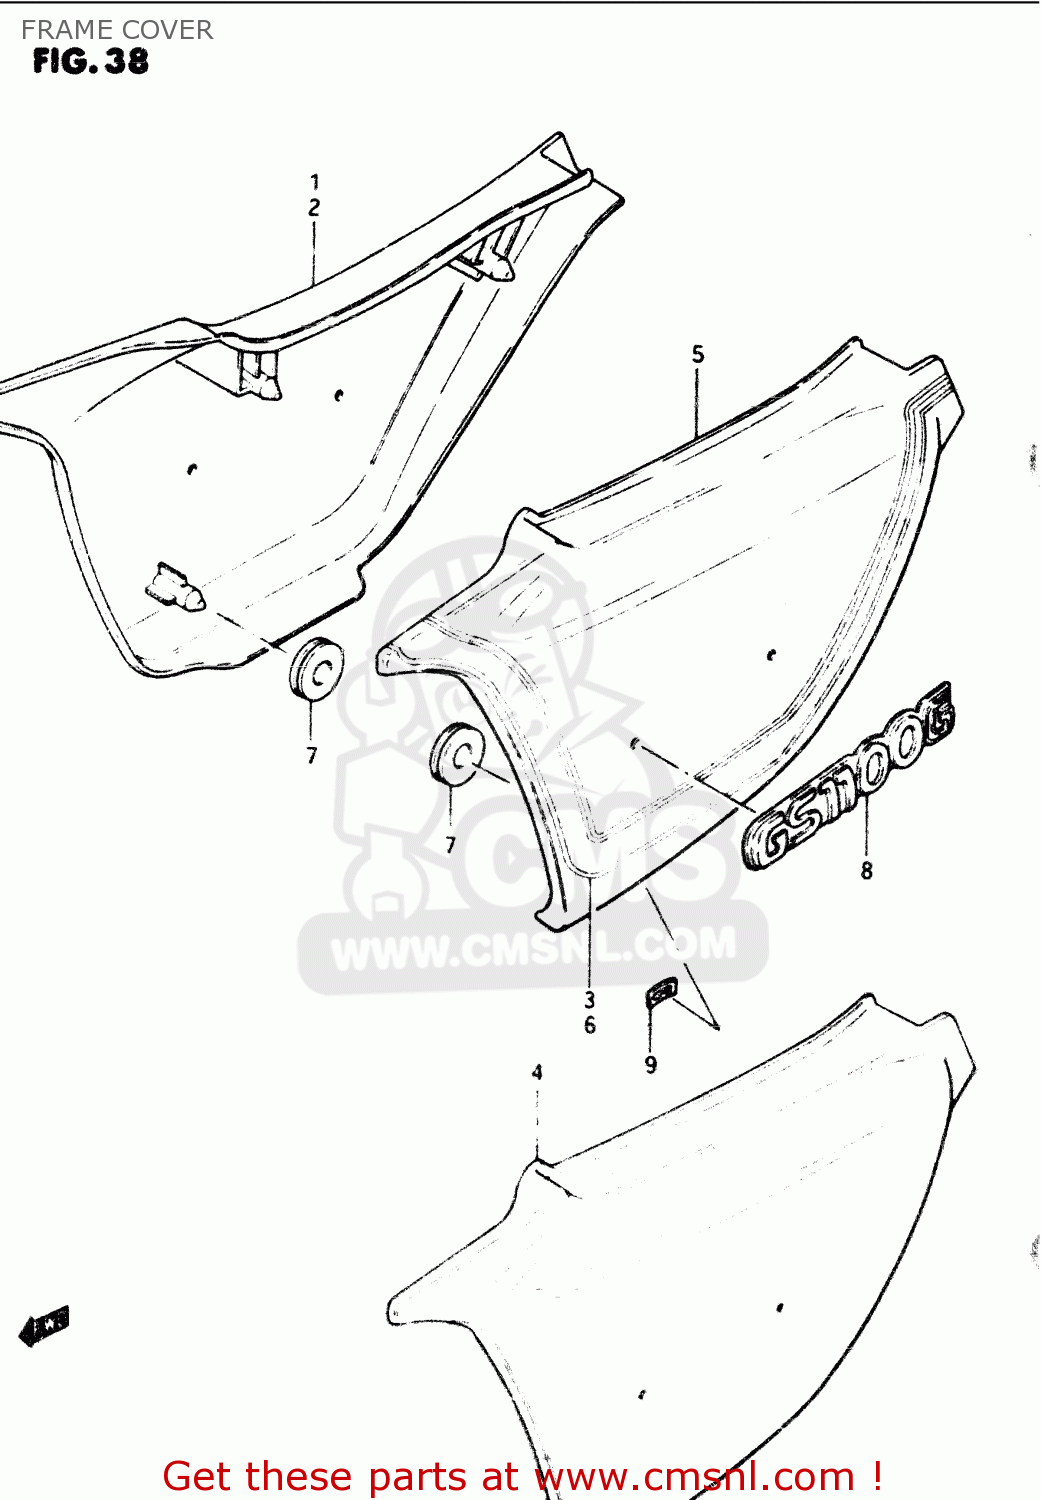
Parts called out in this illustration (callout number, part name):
1	COVER, FRAME RH (RED)
2	COVER, FRAME RH
3	TAPE SET, FRAME COVER RH
4	COVER, FRAME LH (RED)
5	COVER, FRAME LH
6	TAPE SET, FRAME COVER LH
7	CUSHION
8	EMBLEM,FRAME COVER
9	NUT
